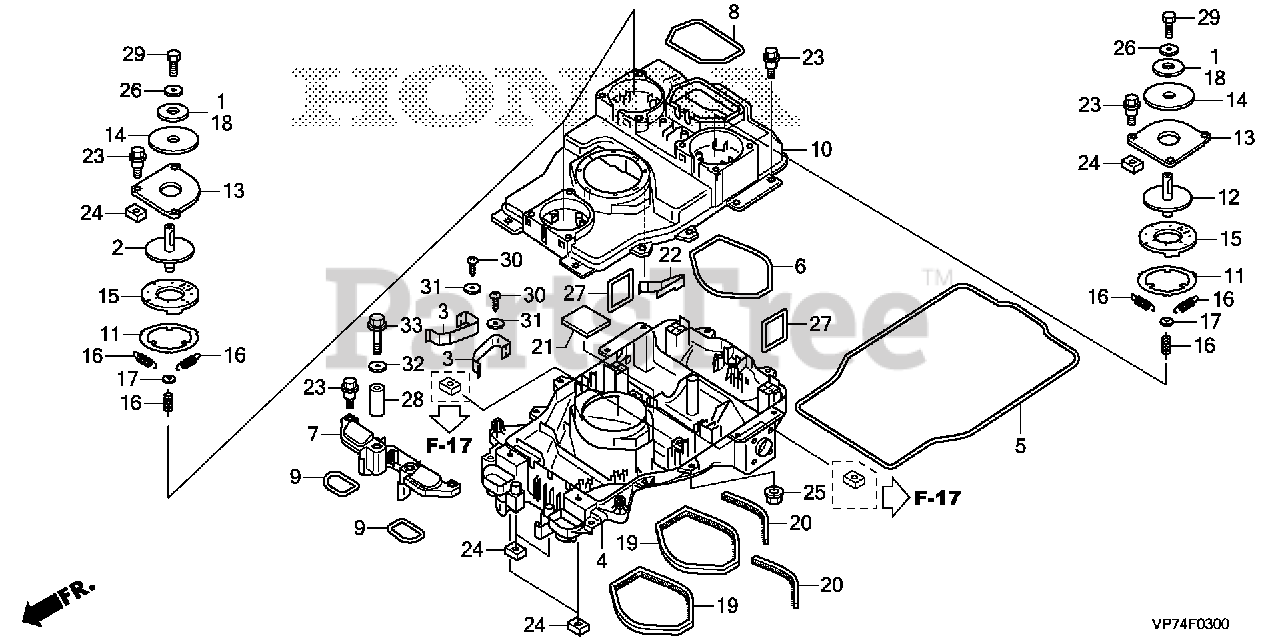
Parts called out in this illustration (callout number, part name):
2	MAGNET, OBSTRUCTION
3	SOCKET, CHARGE
4	FRAME (LOWER)
5	SEAL A, FRAME
6	SEAL B, FRAME
7	COVER, FR. AREA SENSOR
8	SEAL C, FRAME
9	SEAL D, FRAME
10	FRAME (UPPER)
11	PLATE, SPRING
12	SHAFT B, MOUNT
13	PLATE, MOUNT
14	WASHER, LIFT
15	WASHER, MOUNT
16	SPRING, MOUNT
17	WASHER, SPRING
18	RUBBER, MOUNT
19	SEAL, MOTOR HOUSING
20	SEAL C, MOTOR HOUSING
21	MAT, BATTERY
22	PLATE, RATCHET
23	BOLT, FLANGE (6MM)
24	NUT, SPECIAL (6MM)
25	NUT, FLANGE (6MM)
26	WASHER, PLAIN (5MM)
27	O-RING, MOTOR MOUNT
28	COLLAR, CARRY GRIP
29	BOLT, HEX. (5X12)
30	SCREW, TAPPING (4X12)
31	WASHER, PLAIN (4MM)
32	WASHER, PLAIN (6MM)
33	BOLT, FLANGE (6X32)
